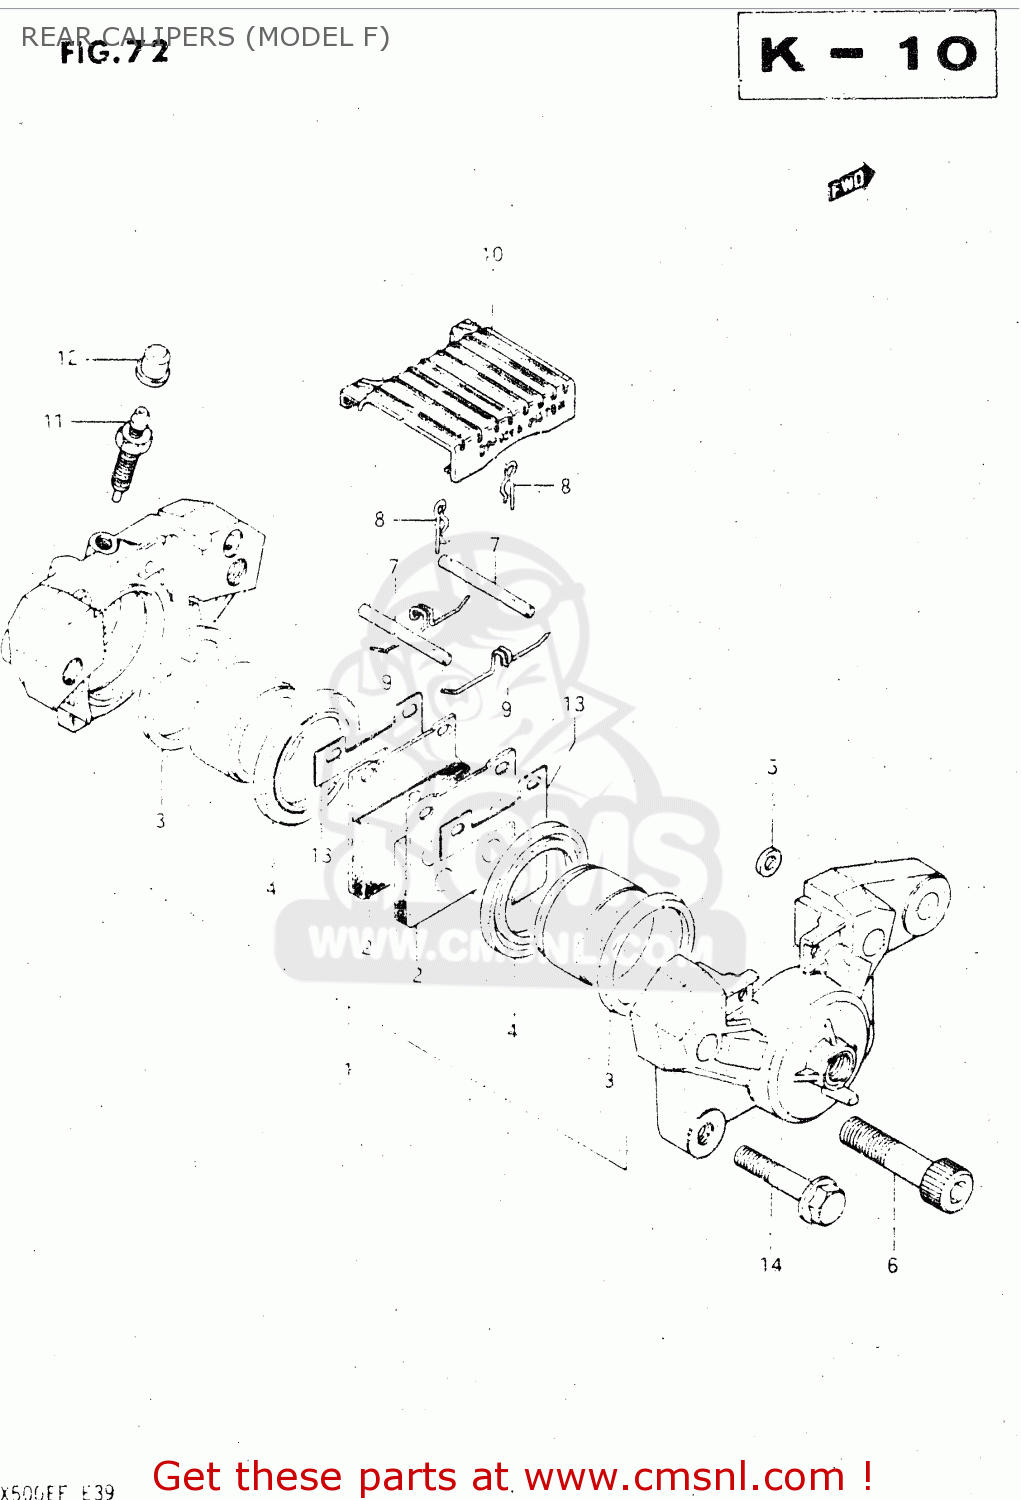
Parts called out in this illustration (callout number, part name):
1	PISTON SET
2	PAD
3	SEAL,PISTON
4	BOOT
5	SEAL,JOINT
6	BOLT,CALIPER HOUSING
7	PIN,PAD
8	CLIP,PAD PIN
9	SPRING
10	COVER,CALIPER
11	BLEEDER
12	CAP,BREATHER
13	SHIM
14	BOLT
